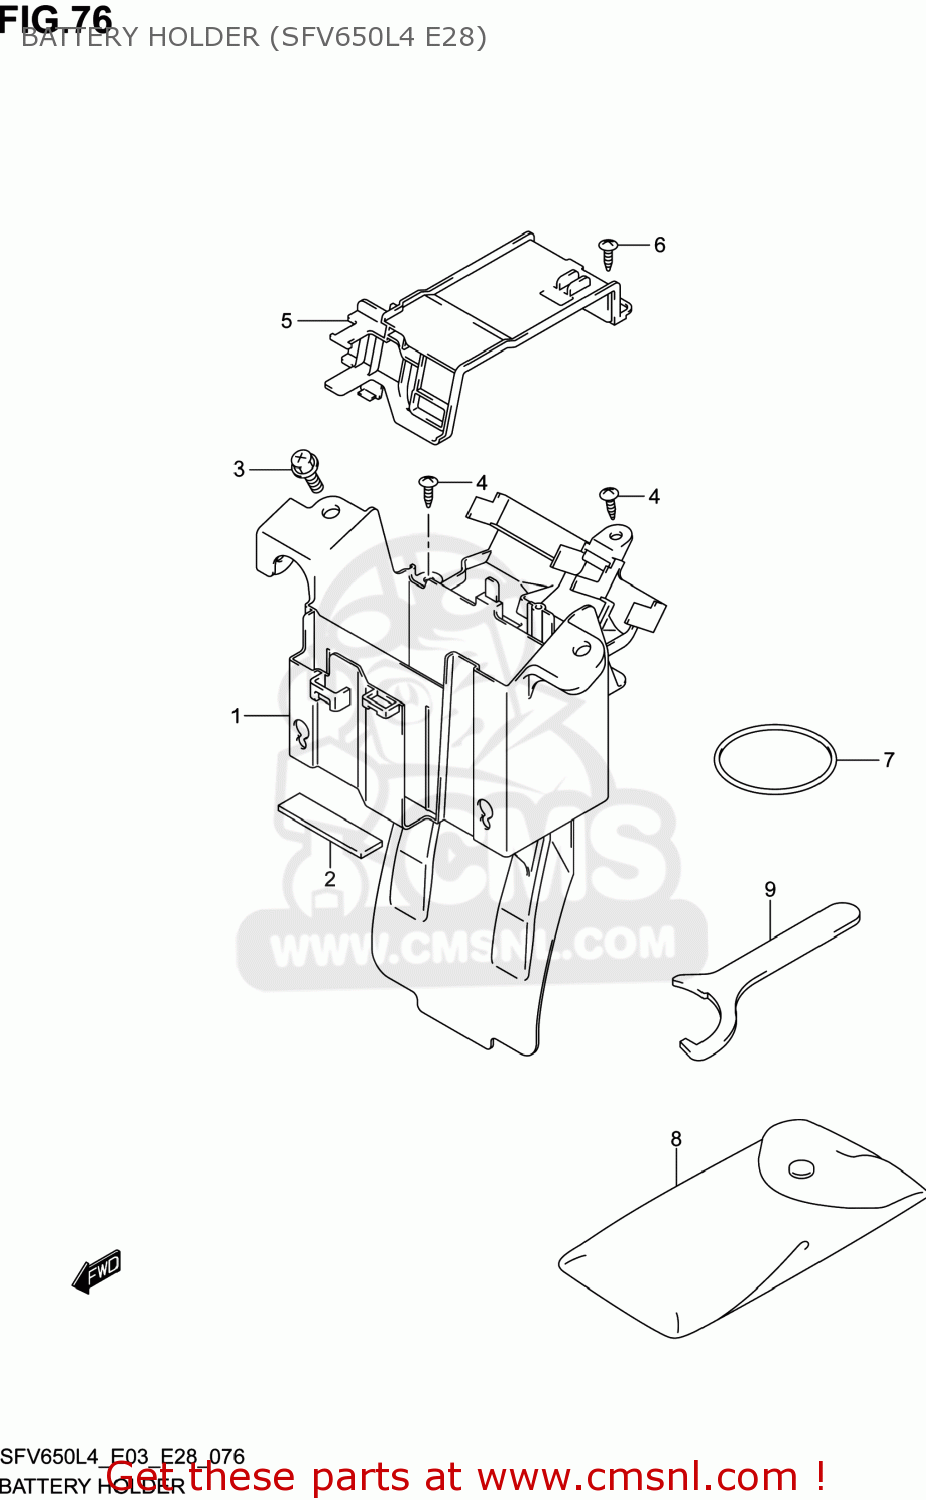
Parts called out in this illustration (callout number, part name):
1	HOLDER,BATTERY
2	CUSHION,FR FENDER
3	BOLT(6X16)
4	SCREW
5	LID,BATTERY HOLDER
6	SCREW
7	O RING(D:3.5,ID:56.5)
8	TOOL ASSY
9	CLAMP
